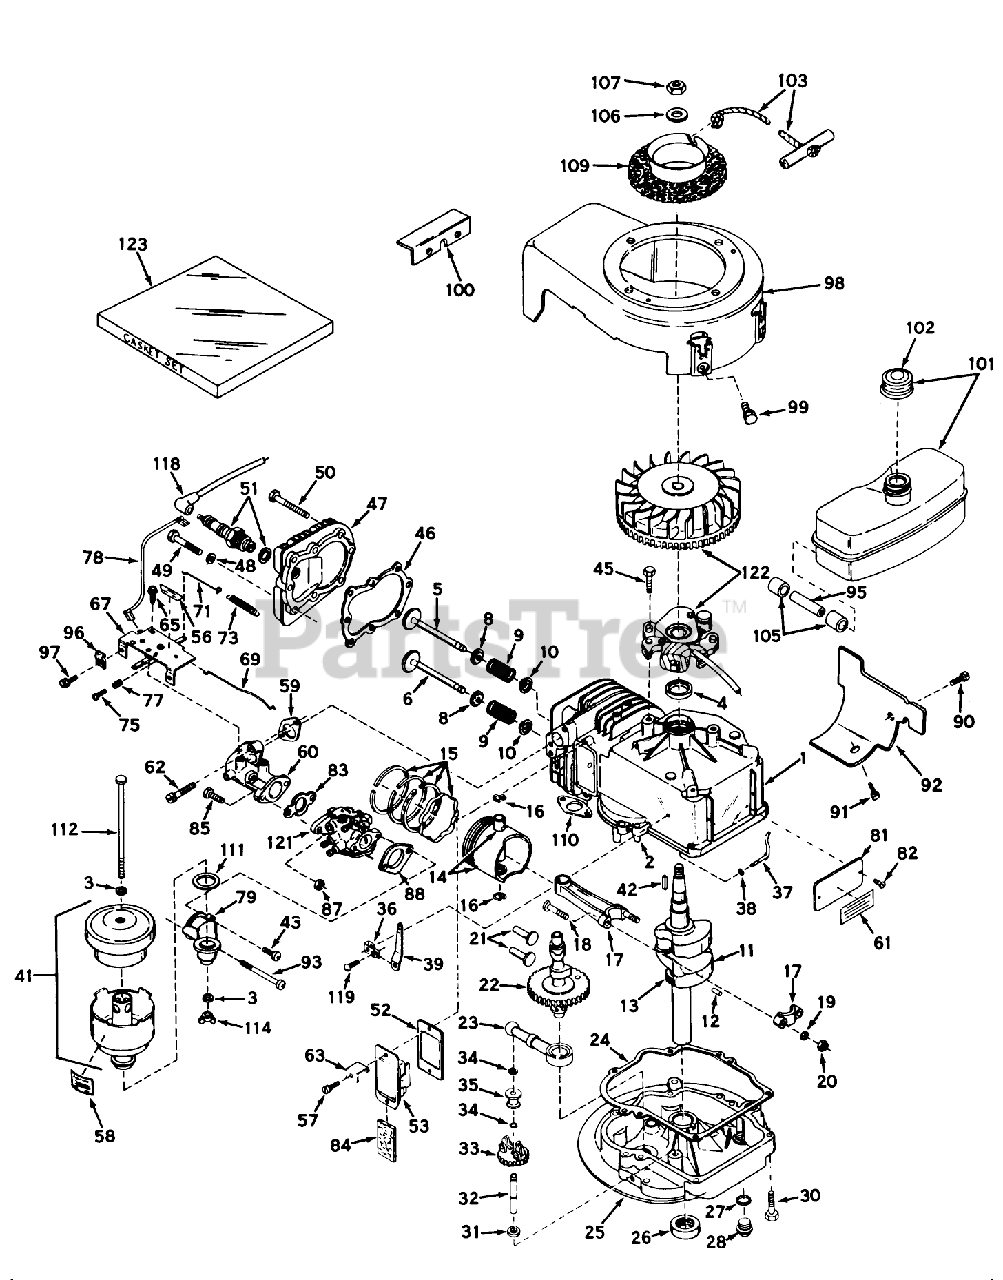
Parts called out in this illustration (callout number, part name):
1	Cylinder Assy. (Incl. Ref. 2 4)
2	Pin-Dowel
3	Washer Fibre
4	OIL SEAL
5	Valve, Intake (Incl. Ref. #38, 39 40) (Std.)
5	Valve, Intake(1/32"overs.)(Incl. Ref. 8, 9 10)
6	Valve, Exhaust (Standard)(Incl. Ref. 8, 9 10)
6	Valve, Exhaust (1/32" Overs.(Incl. Ref. 8, 9 10)
8	Cap-Upper Valve Spring
9	Spring-Valve
10	Cap-Valve, Spring
11	Crankshaft Assy. (Incl. Ref. 12 13)(Model LAV35-40455H)
12	Pin, Groove
13	Gear, Crankshaft
14	Piston Pin Assy. (Incl. 2 of No. 16)(Standard)
14	Piston Pin Assy. (Incl. 2 of No. 16)(.010 oversize)
14	53020 ADN. TO 28594
15	Piston Ring Set Std.
15	Piston Ring Set .010 O.S.
15	Piston Ring Set .020 O.S.
16	Ring-Retaining, Piston Pin
17	Rod Assy., Connecting (Incl. Nos. 18, 19 20)
18	Bolt, Connecting
19	Washer
20	LOCKNUT
21	Lifter-Valve
22	Camshaft
23	Oil Pump ASM
24	Gasket, Mounting
25	Flange Assy., Mounting (Incl. Ref. 26, 27, 28 32)
26	Seal Oil
27	Gasket-Oil Drain
28	Plug, Oil Drain
30	Screw (1/4-20 x 1-1/4)
31	Washer-Flat
32	Shaft-Governor
33	Governor Gear ASM
34	Ring-Retaining
35	Spool-Governor
36	Clamp-Lever, Governor
37	Rod, Governor (Incl. No. 36)
38	Washer-Flat
39	Lever, Governor
41	Cleaner Assy., Air
42	Key Flywheel
43	KIT - SEAL WIPER
45	Screw
46	Gasket-Cylinder Head
47	CYLINDER HEAD
48	Washer
49	Screw
50	Screw
51	SPARK PLUG
52	Gasket Breather
53	Breather Assembly (Incl. Nos. 52 84)
56	Decal
57	Screw
58	Decal, Air Cleaner
59	Gasket, Intake
60	Pipe, Intake
61	480B GIL SNWTHWR O/
62	Screw, Fil. Hd. Sems
63	Retainer Clip
65	Screw (10-24 x 9/16)
67	Control Assy., Speed
69	Link, Throttle to Governor
71	Link, Governor Spring
73	Spring, Governor
75	Screw
77	Spring-Compression
78	Wire, Ground
79	Elbow, Air Cleaner
81	IDENTIFICATION PLATE
82	Stud
83	Gasket
84	Element-Breather
87	Nut and Lock Washer (1/4-28)
88	Gasket
90	Screw
91	Screw
92	Extension, Housing
93	Screw
95	Line, Fuel
96	Conduit
97	Screw (10-32 x 3/8)
98	Housing, Blower
99	Screw (1/4-20x19/32)
100	Bracket, Shroud
101	Tank, Fuel
102	Cap, Fuel Filler
103	Rope Assy., Starter
105	Line-Fuel (8.62)
106	Washer
107	Hex Nut
109	Pulley, Rope Start
110	Gasket Exhaust
111	Gasket, Spacer
112	Bolt, Air Cleaner
114	Nut, Wing
118	Cover-Spark Plug
119	Screw
121	Carburetor
122	Magneto
123	Gasket Set
